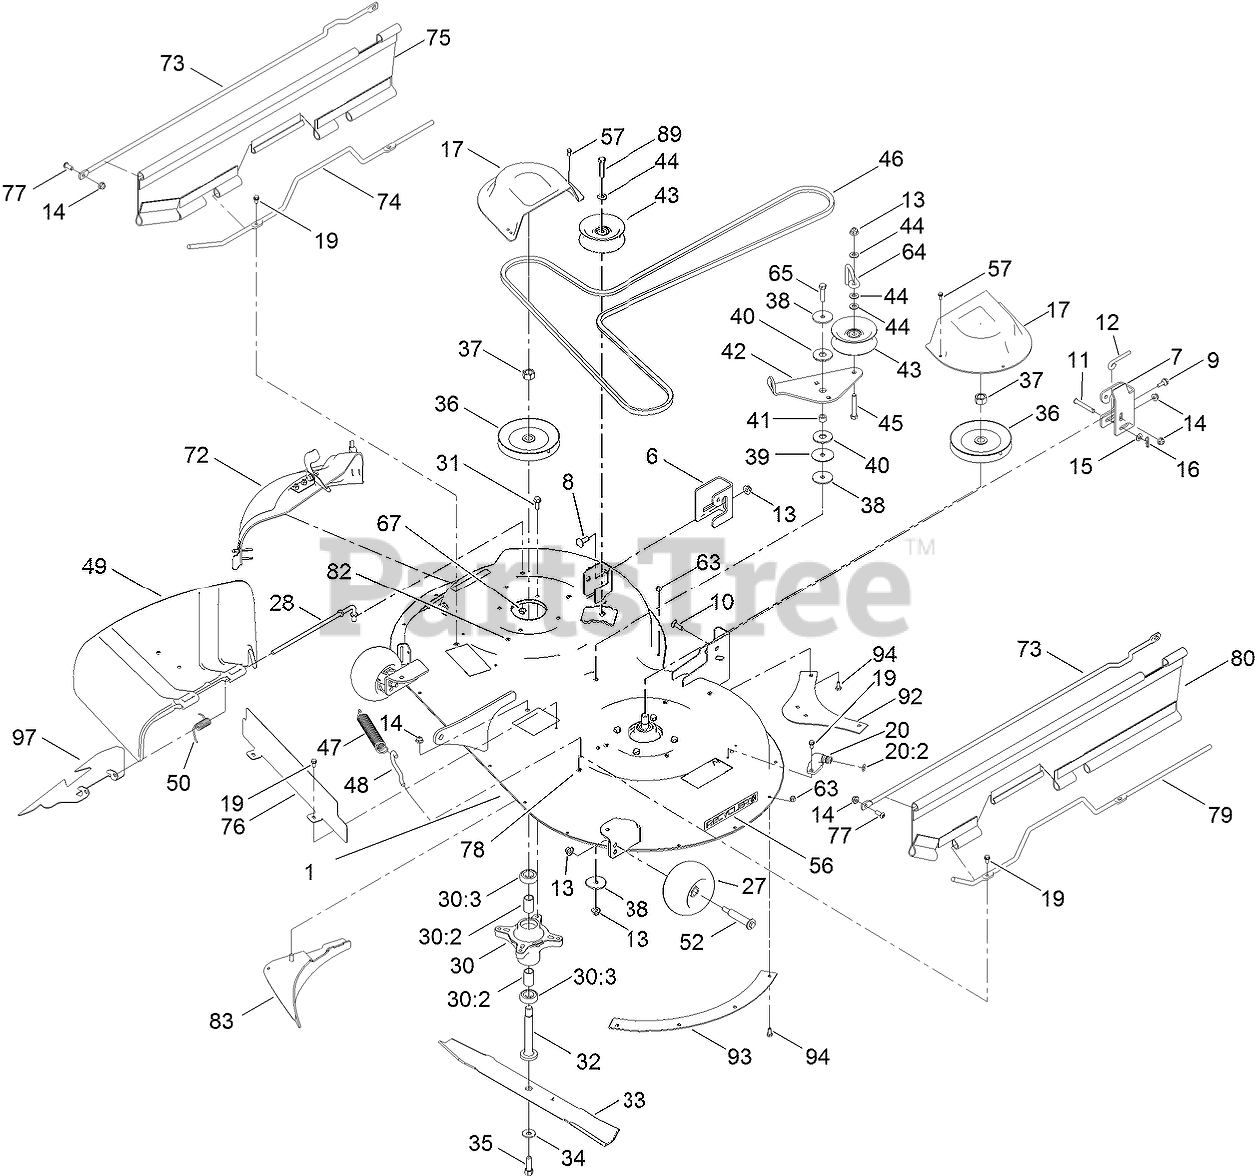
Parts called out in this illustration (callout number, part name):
1	42 INCH DECK AND DECAL ASM
6	Bracket-Hanger, RIGHT REAR
7	Bracket-Hanger, LEFT REAR
10	SCREW-CARR
11	Pin-Clevis
13	NUT-HF, NI
14	NUT-HF
15	WASHER-PLAIN
16	PIN-HAIR
17	COVER-BELT
19	SCREW-HWH
20	FITTING-WASHOUT
20:2	O-RING
27	ROLLER-SCALP, ANTI
28	ROD-PIVOT
30	SPINDLE ASM
30:2	SPACER
30:3	BEARING-BALL
31	SCREW-TAPTITE
32	SHAFT-SPINDLE
33	BLADE-MULCH
34	WASHER-BELLEVILLE
35	SCREW-HH
36	PULLEY
37	Nut-Hex
38	Washer
39	Washer
40	WASHER-FRICTION, COMPOSITE
41	SPACER
42	ARM-IDLER
43	PULLEY-IDLER, FLAT
44	WASHER-FLAT
45	SCREW-HH
46	V-BELT
47	SPRING-EXTENSION
48	HOOK-RETURN SPRING
49	DEFLECTOR
50	SPRING-TORSION
52	BOLT-SHOULDER
56	DECAL-RECYCLER
57	SCREW-TAPTITE
63	NUT-HEX
64	BELT GUIDE - IDLER
65	SCREW-HH
72	42 INCH MULCH PLUG ASM
73	ROD SUPPORT, UPPER
74	ROD-SUPPORT, LOWER (RH)
75	RIGHT GUARD ASM
76	SHIELD-FROUNT
77	SCREW-HSBH
78	NUT-RETAINING
79	ROD-SUPPORT, LOWER (LH)
80	LEFT GUARD ASM
82	NUT-RETAINING
83	BAFFLE-CLIPPING
89	SCREW-HH
92	BAFFLE-BLOWOUT, REAR
93	BAFFLE-BLOWOUT, SIDE
94	SCREW-HH
97	DEFLECTOR-INSERT
